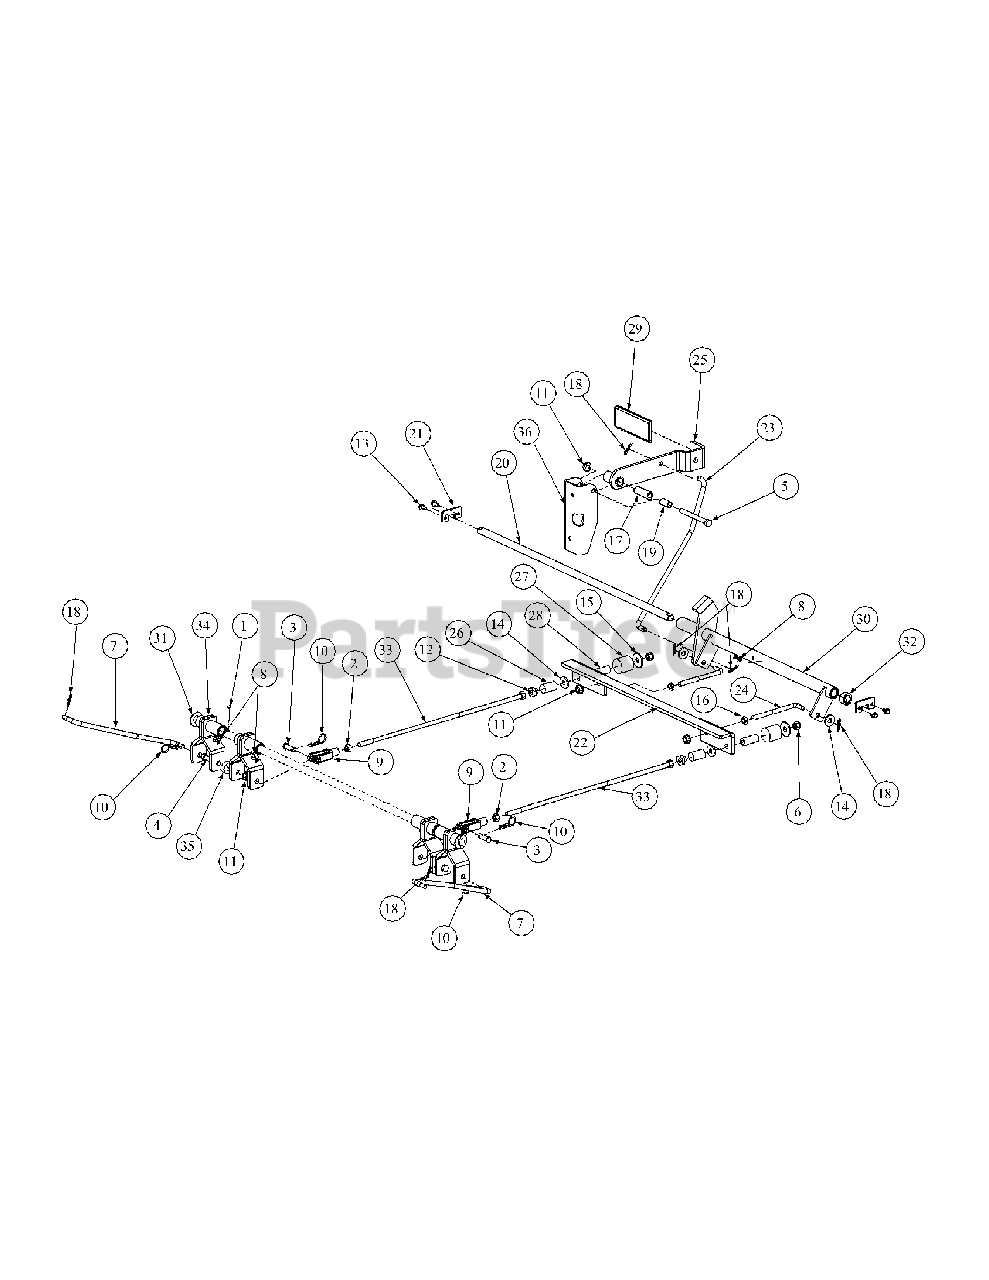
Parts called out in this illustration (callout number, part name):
1	Cotter Pin, .125 x 1.0
2	Hex Nut, 3/8-16
3	Clevis Pin, 3/8 x 1-1/8
4	Hex Cap Screw, 3/8-16 x 1.50
5	Hex Cap Screw, 3/8-16 x 3-1/2
5	Hex Cap Screw, 3/8-16 x 3-1/4
6	Nylock Nut, 3/8-16
7	Linkage Brake Rod
8	Grease Fitting, 1/4 -28, 90°.
9	Yoke, 3/8-16
10	Hair Pin, 3/8" - 1/2"
11	Flange Lock Hex Nut, 3/8-16
12	Shoulder Nut
13	Screw, 1/4-20 x 1-1/2
14	Flat Washer, .406 ID x 1.0 OD x .105
15	Flat Washer, .411 x 1.25 x .100
16	Jam Nut, 3/8-16
17	Spacer, .39 x .63 x 1.75
18	Cotter Pin, .072 x 1.12 Lg
19	Spacer, .375 x .50 x 1.02 Lg
19	Spacer, .375 x .50 x .75 Lg
20	Bellecrank Mounting Shaft
21	Parking Brake Shaft Holder
22	Brake Bracket
23	Brake Rod
24	Connector Rod, 3/8 OD x 5.75
25	Brake Handle
26	Neutral Brake Spring
27	Force Brake Spring
28	Center Brake Hose
29	Parking Brake Grip
30	Brake Bearing Hub
31	Flat Washer, 5/8
32	Shaft Collar, .625 ID x 1" OD x .438
33	Connector Rod, 3/8 OD x 17.88 Lg
34	Rear Brake Arm Assembly
35	Spacer, .406 x 1.00 x .38
36	Park Brake Mounting Bracket
